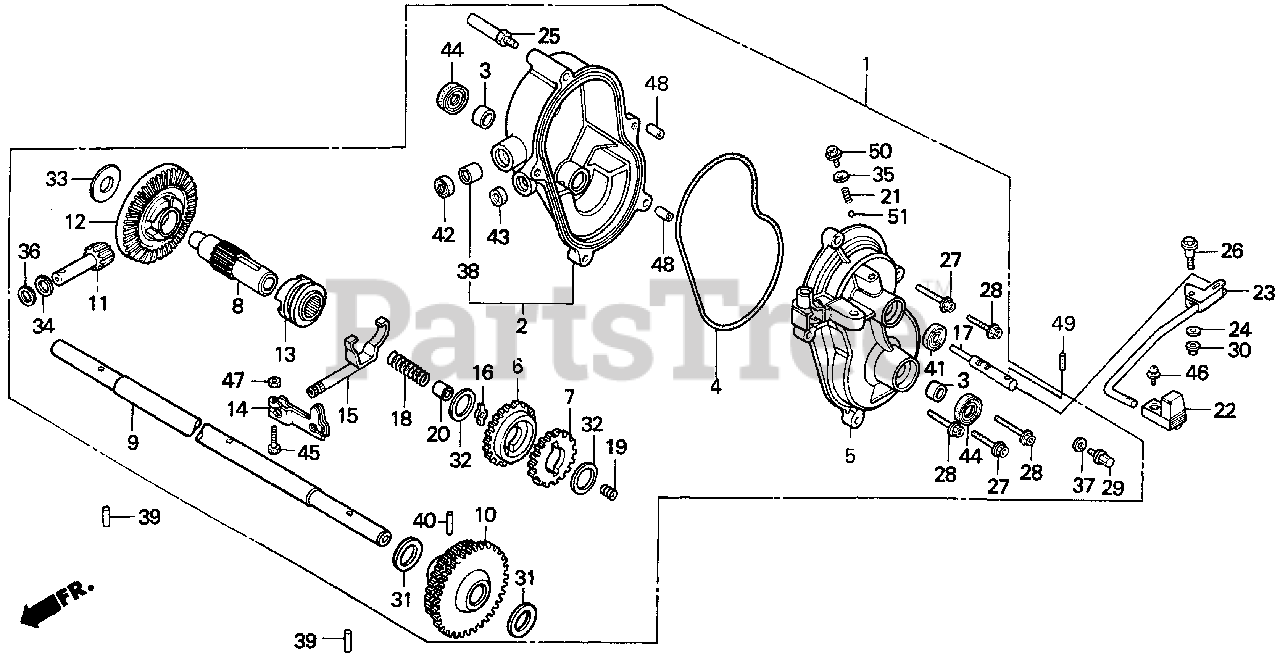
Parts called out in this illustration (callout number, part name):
1	TRANSMISSION ASSY.
2	CASE, R. TRANSMISSION
3	BUSH, TRANSMISSION CASE
4	O-RING, TRANSMISSION CASE
5	CASE, L. TRANSMISSION (NOT AVAILABLE)
6	GEAR, HIGH DRIVE (28T)
7	GEAR, LOW DRIVE
8	COUNTERSHAFT
9	SHAFT, FINAL
10	GEAR, FINAL
11	PINION, BEVEL
12	GEAR, BEVEL (44T)
13	CLUTCH, DRIVEN
14	ARM, CLUTCH
15	SHAFT, SHIFT
17	SLIDER, SHIFT
18	SPRING, SHIFT
19	SPRING, HIGH GEARSHIFT
20	RETAINER, SHIFT SPRING
21	SPRING, BALL SETTING
22	KNOB, CHANGE LEVER
23	LEVER, CHANGE
24	PLATE, ADJUSTING
25	BOLT, GUIDE
26	BOLT, TANK SETTING
27	BOLT, FLANGE (6X28)
28	BOLT, FLANGE (6X25)
29	BOLT, DRAIN PLUG
30	NUT, NYLON RING (6MM)
31	WASHER, THRUST (17.2MM)
32	WASHER, THRUST (19.5MM)
33	WASHER, THRUST (12MM)
34	WASHER (10X21)
35	WASHER, SEALING (6.2X12X1.2)
36	SHIM, BEVEL PINION (A)
36	SHIM, BEVEL PINION (B)
36	SHIM, BEVEL PINION (C)
37	WASHER, DRAIN PLUG (10.2MM)
38	BEARING, NEEDLE (10X17X20)
39	ROLLER (5X23.8)
40	ROLLER (6X25)
42	OIL SEAL (10X17X4) (ARAI)
42	OIL SEAL (10X17X4)
43	OIL SEAL (8X14X5)
44	OIL SEAL (17X26X6)
45	BOLT, HEX. (5X20)
46	SCREW-WASHER (4X12)
47	NUT, HEX. (5MM)
48	PIN, DOWEL (8X14)
49	PIN, SPRING (4X20)
50	BOLT, FLANGE (6X10)
51	BALL, STEEL (#6) (3/16)
